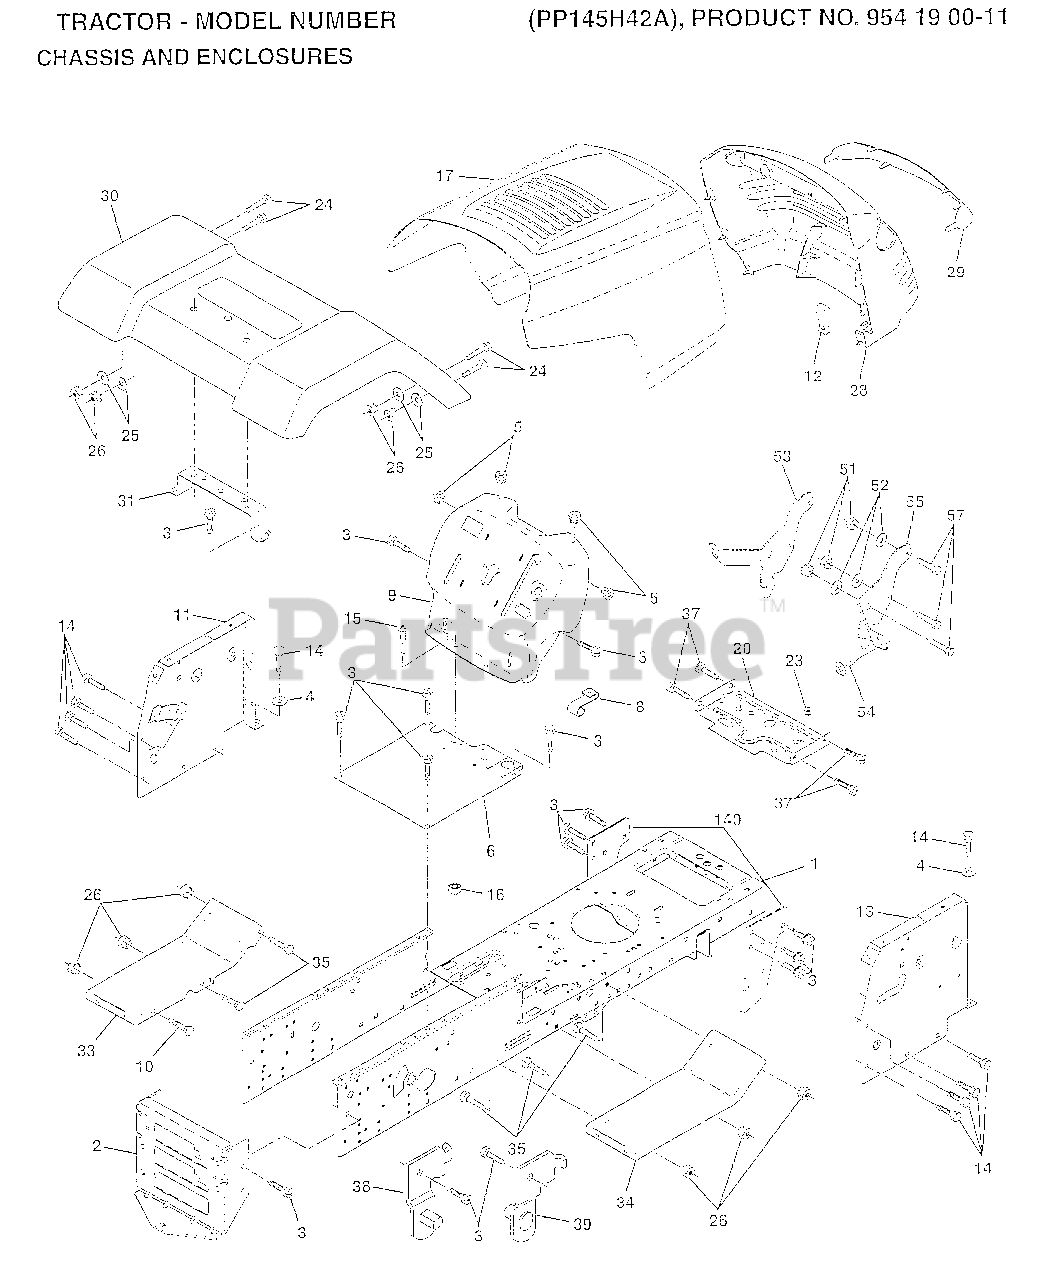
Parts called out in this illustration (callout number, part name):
1	CHASSIS ASM
3	SCREW
4	WASHER
5	BUMPER-HOOD/DASH
6	SADDLE
8	CLIP.RETAINER
9	DASH.PANEL.ASSY
11	"PANEL-DASH,LH"
12	CLIP.TINNERMAN
13	"PANEL-DASH,RH"
14	SCREW LT
15	SCREW
20	"PLATE-MTG,BATT/FU"
24	BOLT
25	WASHER
26	NUT
28	GRILLE-MS428
29	LENS GRILLE
30	FENDER PNT LT W
31	BRKT FENDER
33	FOOTREST.LH.LT/GT
34	FOOTREST.RH.LT/GT
35	BOLT
37	SCREW LT
38	BRACKET ASM LH
39	BRACKET ASM RH
51	NUT
52	WASHER
53	BRACKET.GRILLE.LH
55	BRACKET.GRILLE.RH
140	BRKT SUSPENSION
